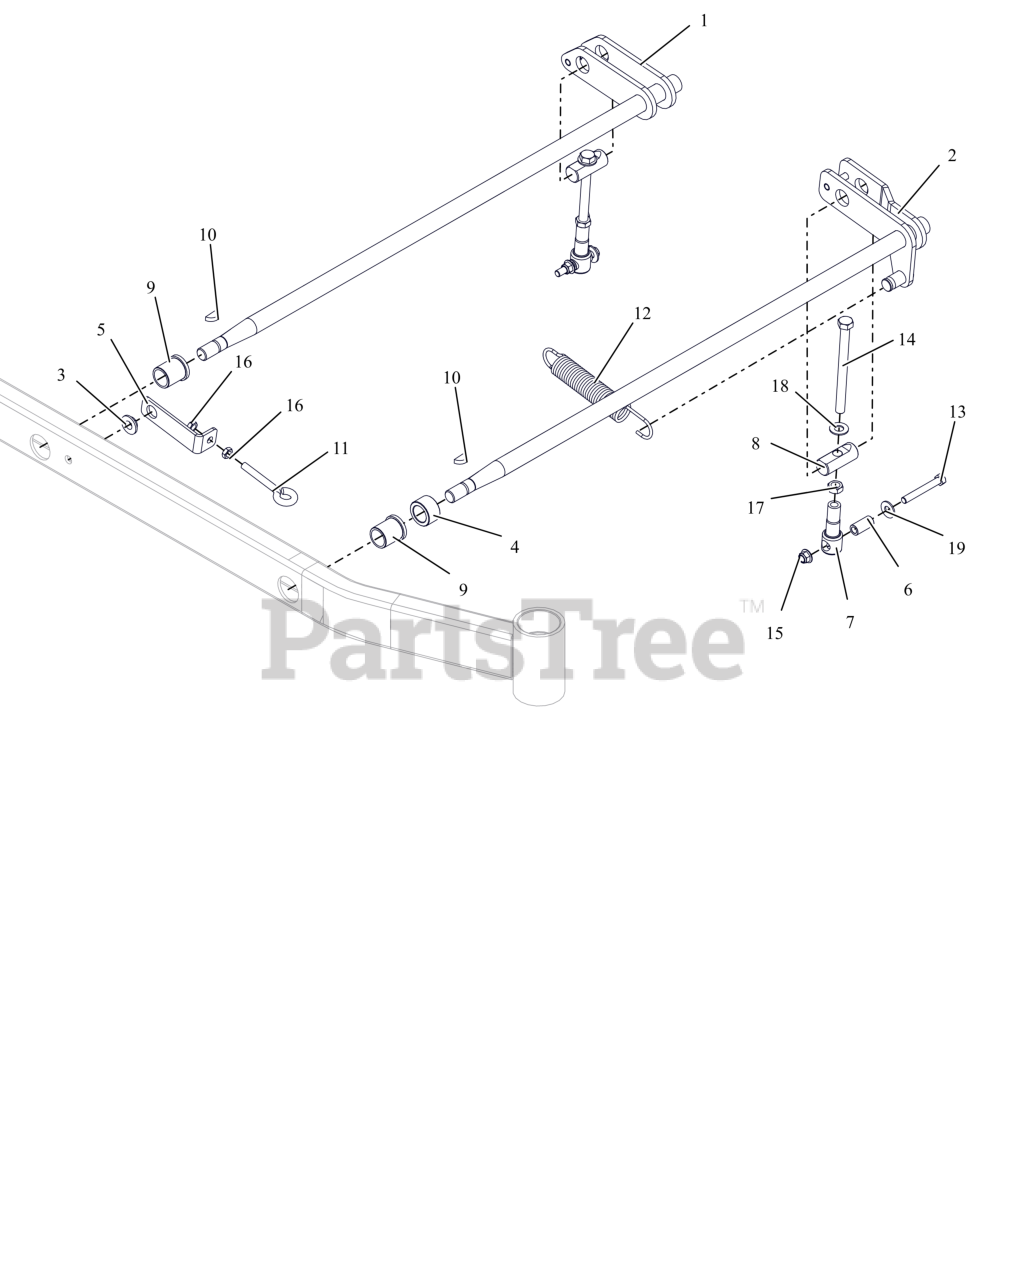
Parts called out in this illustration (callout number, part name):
1	REAR LH DECK LIFT ARM WMT- LF
2	FRT LH DECK LIFT ARM WMT- LF
3	BSHG-FLG .515X.750X.310X1.120
4	SPACER, 1.500 X 1.000 X .880
5	SPRING ANCHOR BRACKET - RED
6	SPACER, DECK LEVELING
7	LINK, DECK LIFT FORMED
8	PIN, DECK LIFT
9	BSHG-FLG 1.00X1.25X1.50X1.50
10	KEY-WDRF .25X1.00 HRD #15
11	BLT-EYE .375-16X2.50 YWZC
12	SG-TENS .162X1.25X8.25 WLD 25
13	BLT, HEX .38-16X2.75 G8 ZCC
14	BLT, HEX .50-13X6.00S G5 ZCC
15	NUT,NYL-FLG .38-16 GF ZCC
16	NUT-JAM .375-16 G2 ZCC
17	NUT-JAM .500-13 G2 ZCC
18	WSHR, FLT .557X1.040X.102 ZCC
19	WSHR,FLT .438X1.00X.083 ZCC
